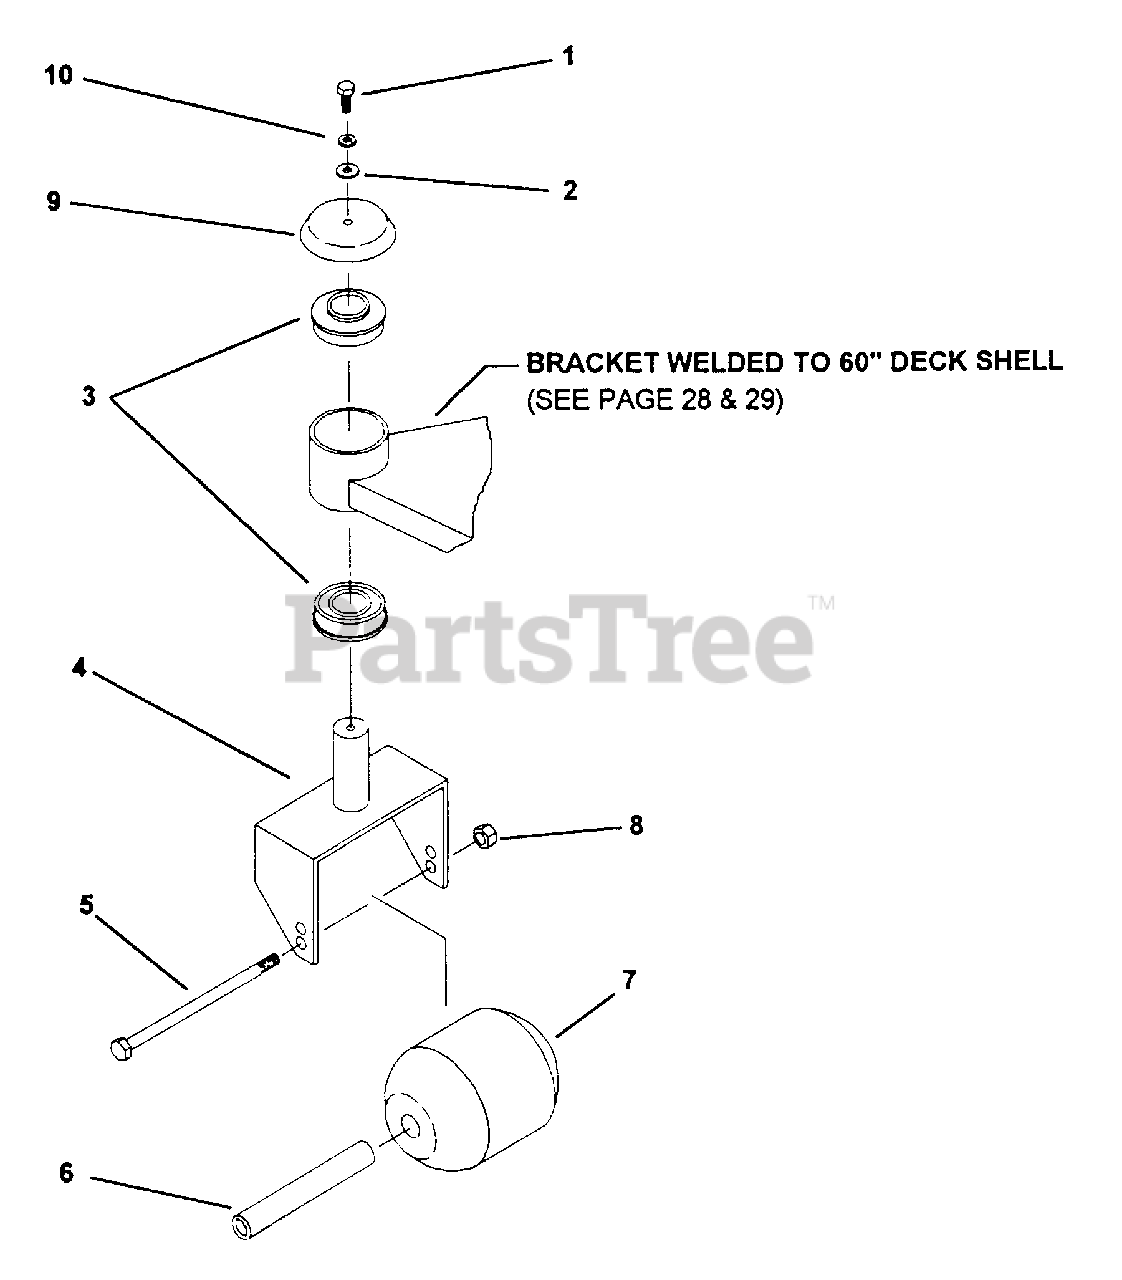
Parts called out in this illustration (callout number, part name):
1	BOLT, 1/4-20 X 3/4" GR. 5
2	WASHER, FLAT STD. 1/4"
3	BEARING, SPD SF-16-32 NO/COLLAR
4	SWIVEL YOKE WELDMENT
5	BOLT, 3/8-16 X 6" GR. 5
6	BUSHING
7	ROLLER, 3-3/4" X 4-13/16" LONG
8	NUT, 3/8-16 NYLOC
9	CAP, BEARING
10	LOCKWASHER, 1/4" SPLIT SPRING
